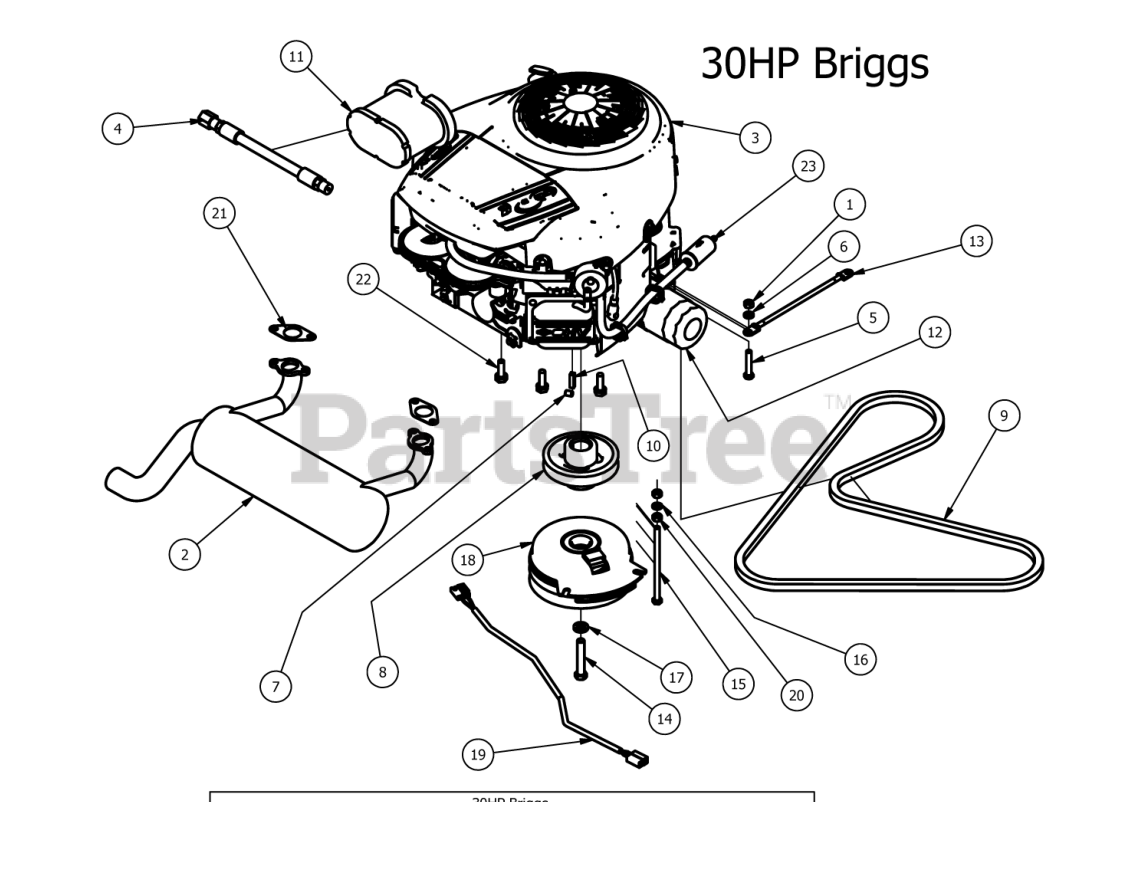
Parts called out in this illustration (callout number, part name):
2	Exhaust- Stand On (30hp Briggs)
3	30 hp Briggs Engine W/Cyclonic Filter
4	Oil drain Hose
5	5/16" x 1 3/4" Hex Bolt
6	5/16" Lock Washer
7	3/8" Set Screw
8	4 3/4 Motor Pulley
10	1/4" x 1" Key
11	30hp Briggs Air Filter
12	Oil Filter
13	Starter to chassis cable
14	7/16" x 2 1/2" Hex Bolt
15	5/16-18 x 5-1/2 GR 5 Hex Bolt
16	5/16" Lock Washer
17	7/16" Lock Washer
18	Clutch Assembly
19	Clutch Pigtail
21	Exhaust gasket
22	3/8 x 1 1/8 bolt
23	Universal Inline Fuel Filter
